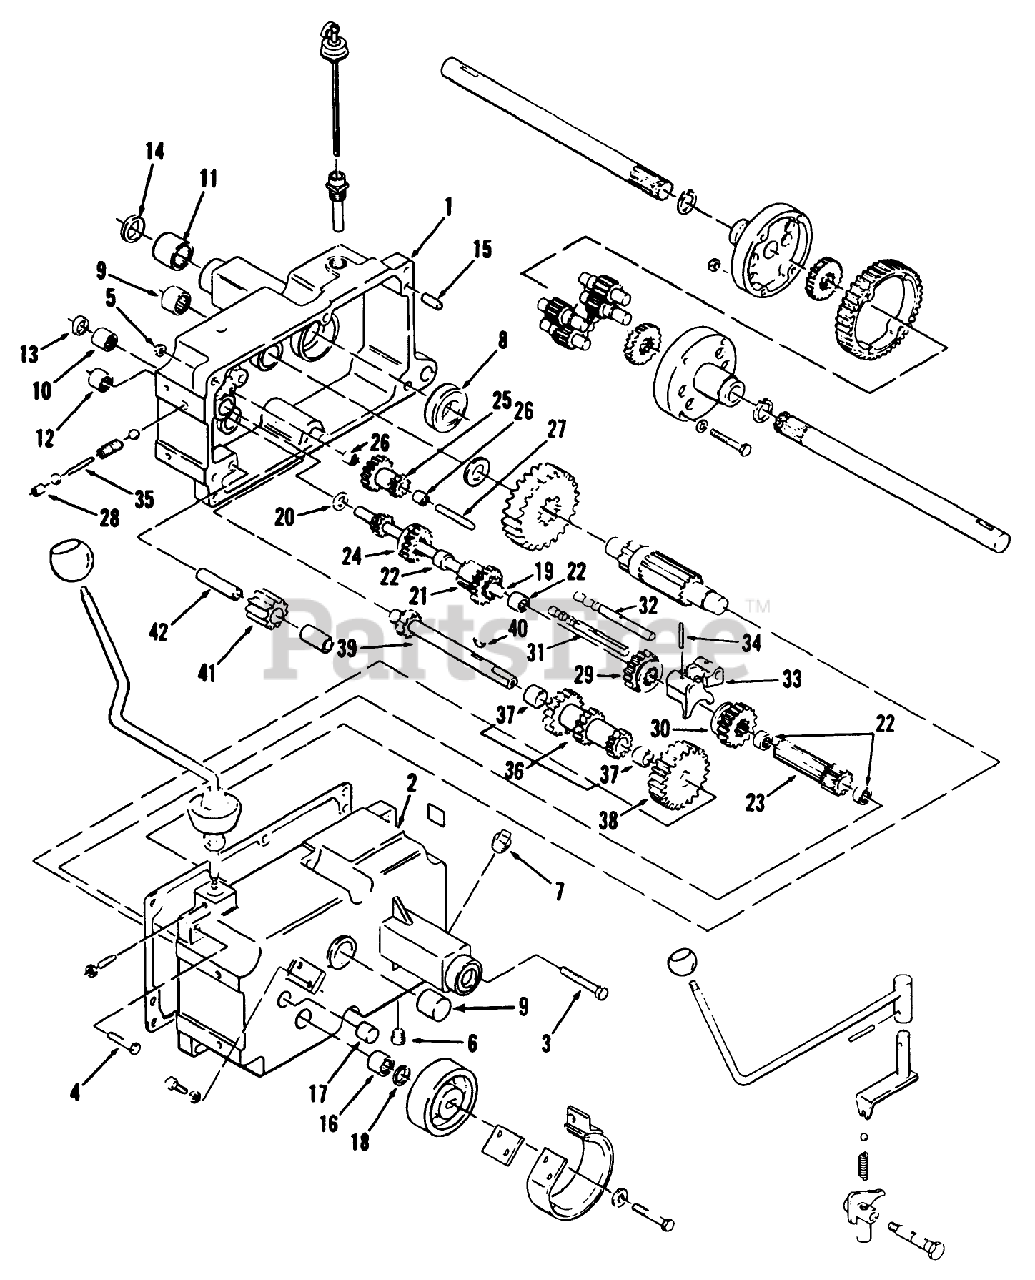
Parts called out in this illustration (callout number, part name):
1	CASE TRANS RH
3	SCREW-HH
4	SCREW-HH
5	NUT-LOCK, NI
7	PLUG-PIPE, SQH
8	BEARING-BALL
9	BEARING-NEEDLE
10	BEARING-NEEDLE
11	BEARING-NEEDLE
12	BEARING-NEEDLE
13	SEAL-OIL
14	OIL SEAL
15	PIN-DOWEL
16	BEARING-NEEDLE
18	SEAL-OIL
19	SHAFT-INPUT
20	WASHER-THRUST
21	GEAR
22	BEARING-NEEDLE
23	GEAR
24	GEAR-SLIDING
26	BEARING-NEEDLE
27	GEAR-SHAFT REDUCTION
28	CUP-PLUG
29	GEAR-HI AND 2ND
30	GEAR-LOW AND REVERSE
31	RAIL-SHIFT
32	RAIL-REAR SHIFT
33	FORK-SHIFT
34	PIN-ROLL
35	PIN-SHIFT
36	GEAR-CLUSTER
37	BUSHING-BRONZE
38	GEAR-CLUSTER SHAFT
40	KEY-WOODRUFF
41	GEAR/BUSHING ASM-REVERSE IDLER
42	PIN-DIFFERENTIAL
